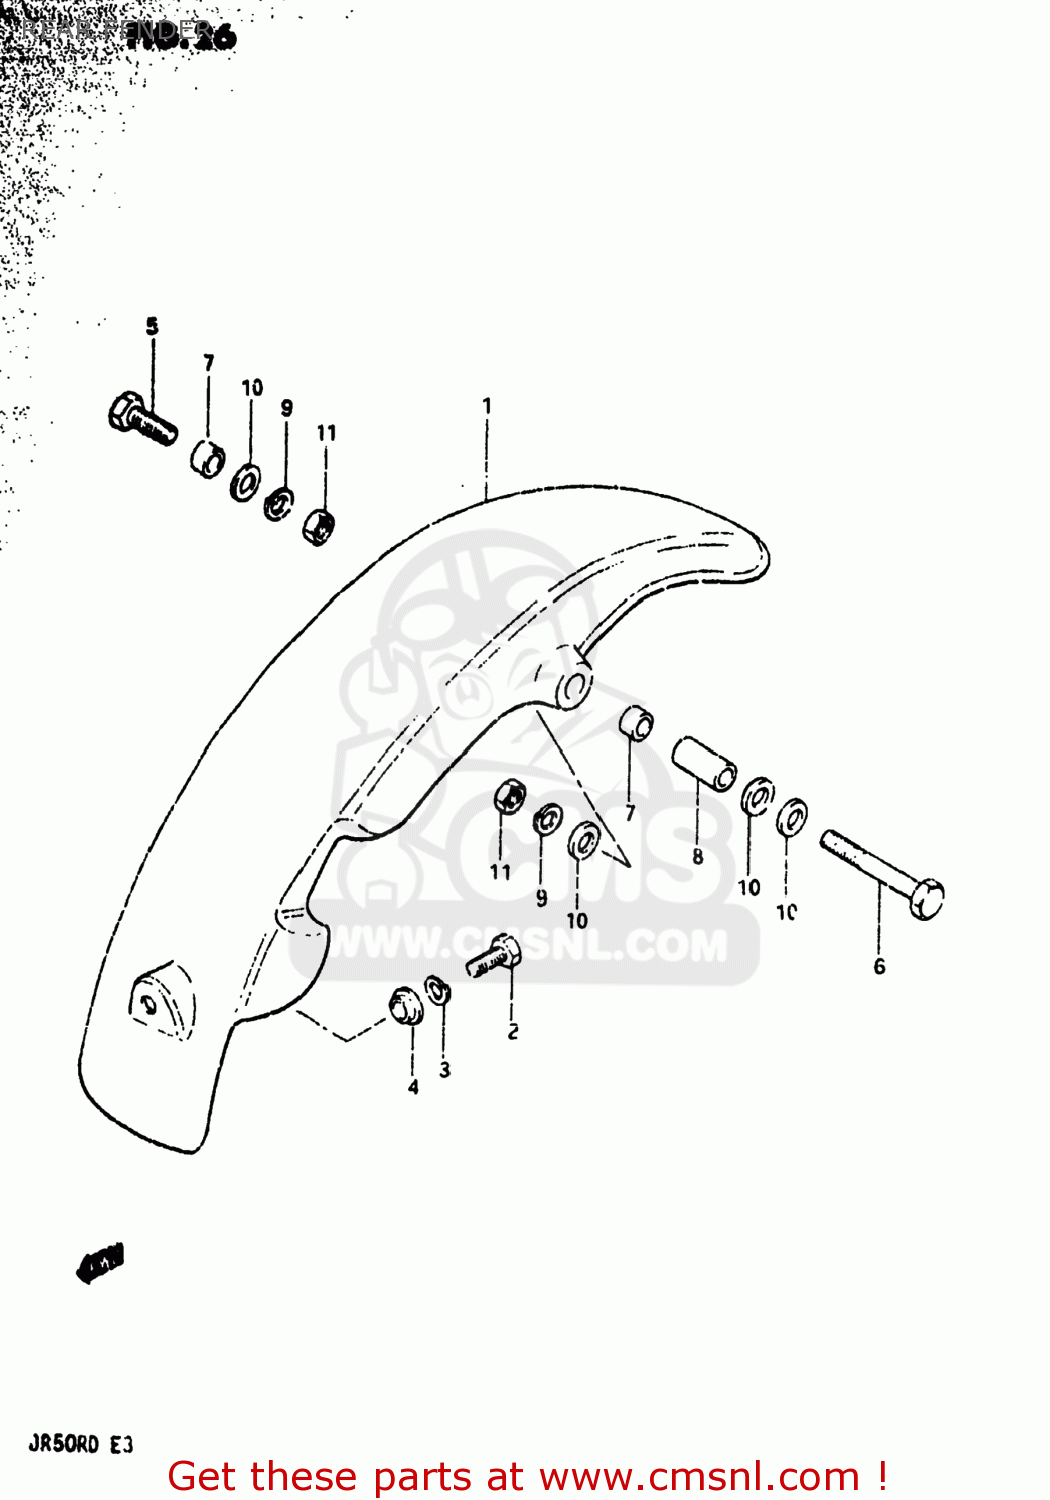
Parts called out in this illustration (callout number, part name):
1	FENDER,REAR
2	BOLT
3	LOCK WASHER
4	WASHER
5	BOLT
6	BOLT 8X50
7	SPACER,RR FENDER RR
8	SPACER (8.2X12.5X23.5)
9	LOCK WASHER
10	WASHER
11	NUT
